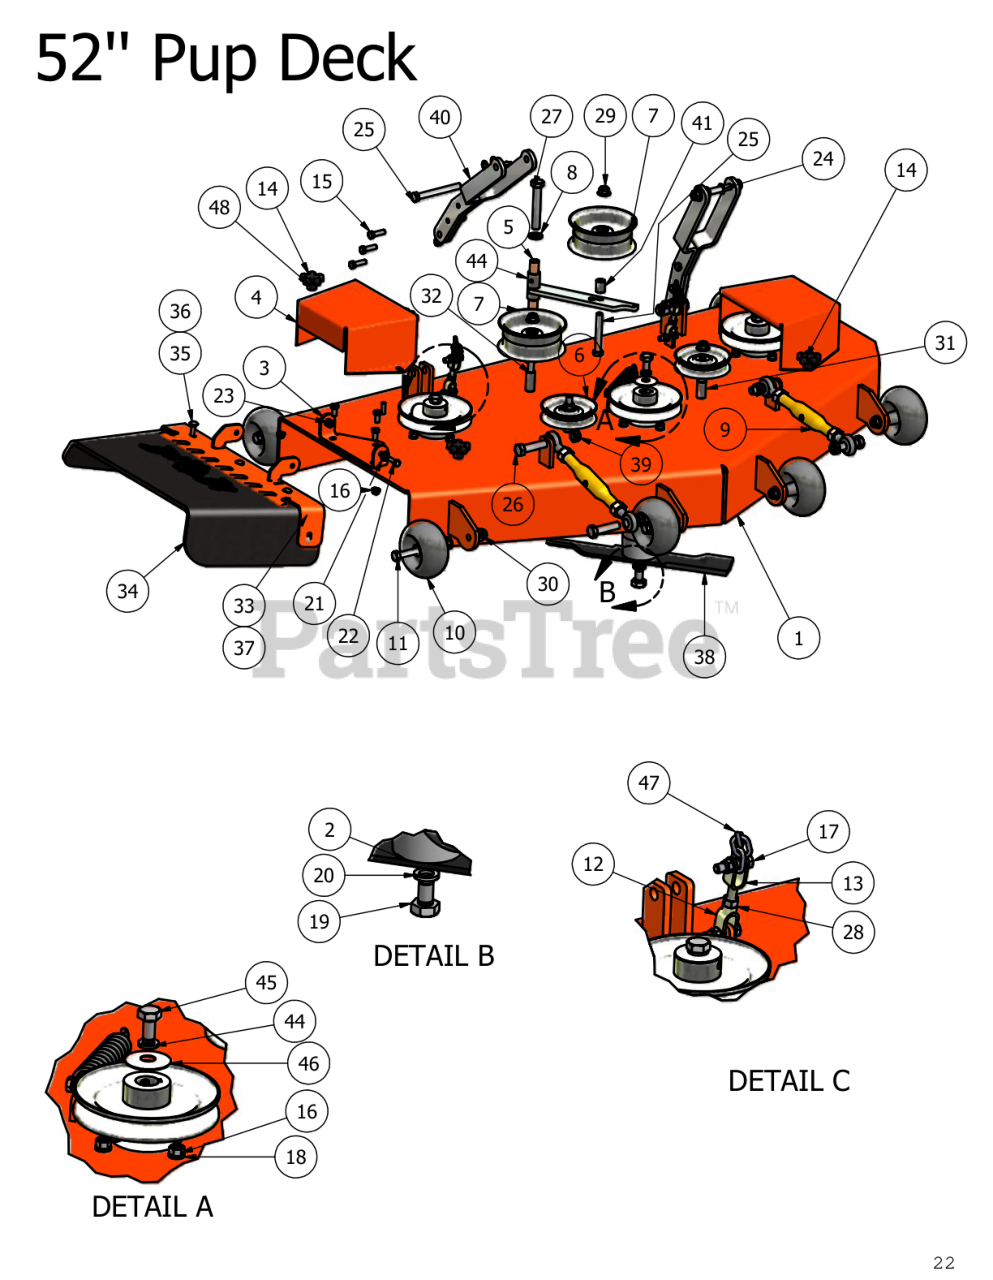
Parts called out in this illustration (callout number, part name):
2	Spindle ('04 and Up)
3	Discharge Chute Hanger
4	Pulley Cover
5	5/8" ID x 1 1/8" Bushing
6	4 3/4" Idler Pulley
7	5 3/4" Flat Idler Pulley
8	.635 ID Plastic Washer
9	Turnbuckle (Top Link)
10	Anti-Scalp Roller
11	1/2" x 4" Bolt
12	Female Yoke
14	5/16" Knob
15	3/8" x 3/4" Hex Bolt
16	3/8" Hex Nut
17	3/8" x 1 1/4" Hex Bolt
18	3/8" Lock Washer
19	5/8" x 1 1/2" Fine Threaded Bolt
20	5/8" Lock Washer
21	.360 ID Plastic Washer
22	5/16" x 1" Hex Bolt
23	5/16" Nylock
24	1/2" Brass Washer
25	1/2" x 4 1/2" Bolt
26	5/8" x 2 1/2" Hex Bolt
27	5/8" x 4" Hex Bolt
28	3/8" Hex Nut
29	1/2" Flange Lock Nut
30	3/8" Flange Nut
31	1 1/2" Pulley Spacer
32	1 3/4"Pulley Spacer
33	Upper Hanger
34	Rubber Side Discharge
35	5/16" x 1 1/2" Carriage Bolt
36	5/16" Nylock Flange Nut
37	Lower Hanger
38	16 1/4" Bad Boy Blade
39	5/8" Nylock (1/2" Jam)
40	Deck Support Arm
41	Pup Pulley Spacer
42	1" Collar Spacer
43	2009 Deck Idler
44	1/2" Lock Washer
45	1/2" x 1 1/2" Bolt
46	Cup Washer
